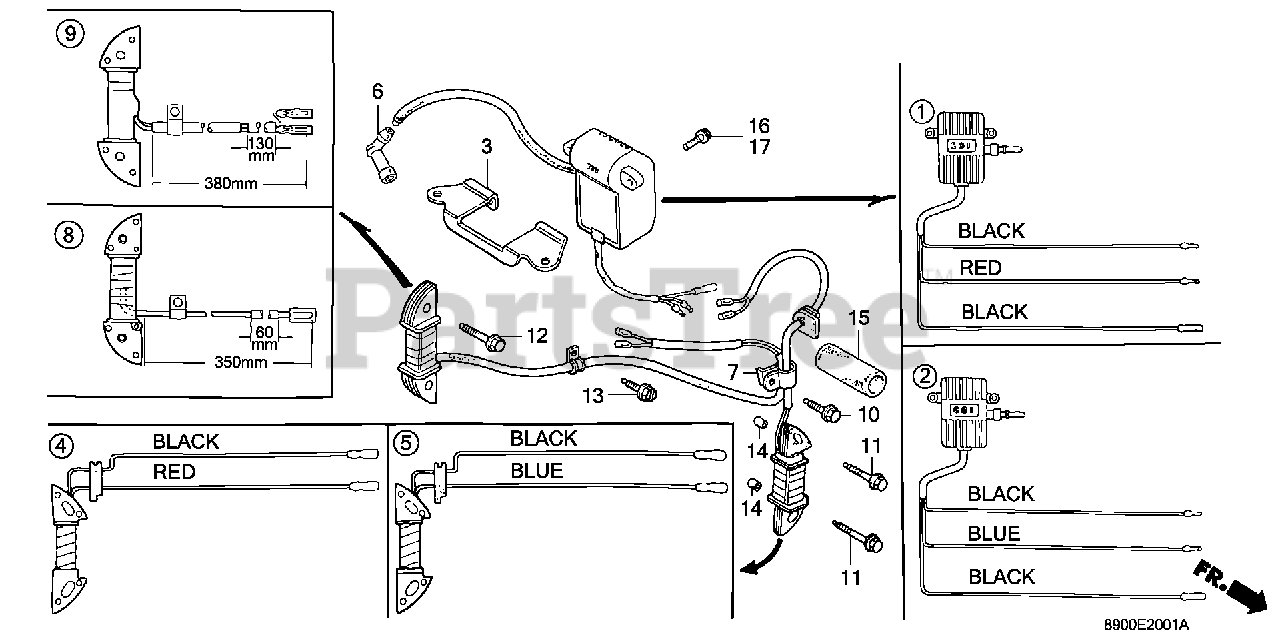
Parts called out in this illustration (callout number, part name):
1	MODULE, IGNITION CONTROL (CDI)
1	MODULE, IGNITION CONTROL (CDI) (NOT AVAILABLE)
3	STAY, IGNITION CONTROL MODULE (CDI)
4	COIL ASSY., EXCITER
6	CAP ASSY., NOISE SUPPRESSOR
6	CAP ASSY., NOISE SUPPRESSOR (NOT AVAILABLE)
7	CLAMP, IGNITION WIRE
10	BOLT, FLANGE (6X12) (CT200)
11	BOLT, FLANGE (6X28) (CT200)
14	PIN, DOWEL (8X14)
15	TUBE, VINYL (22X27X60) (95003-60001-10M) (NOT AVAILABLE)
16	BOLT, FLANGE (6X12)
